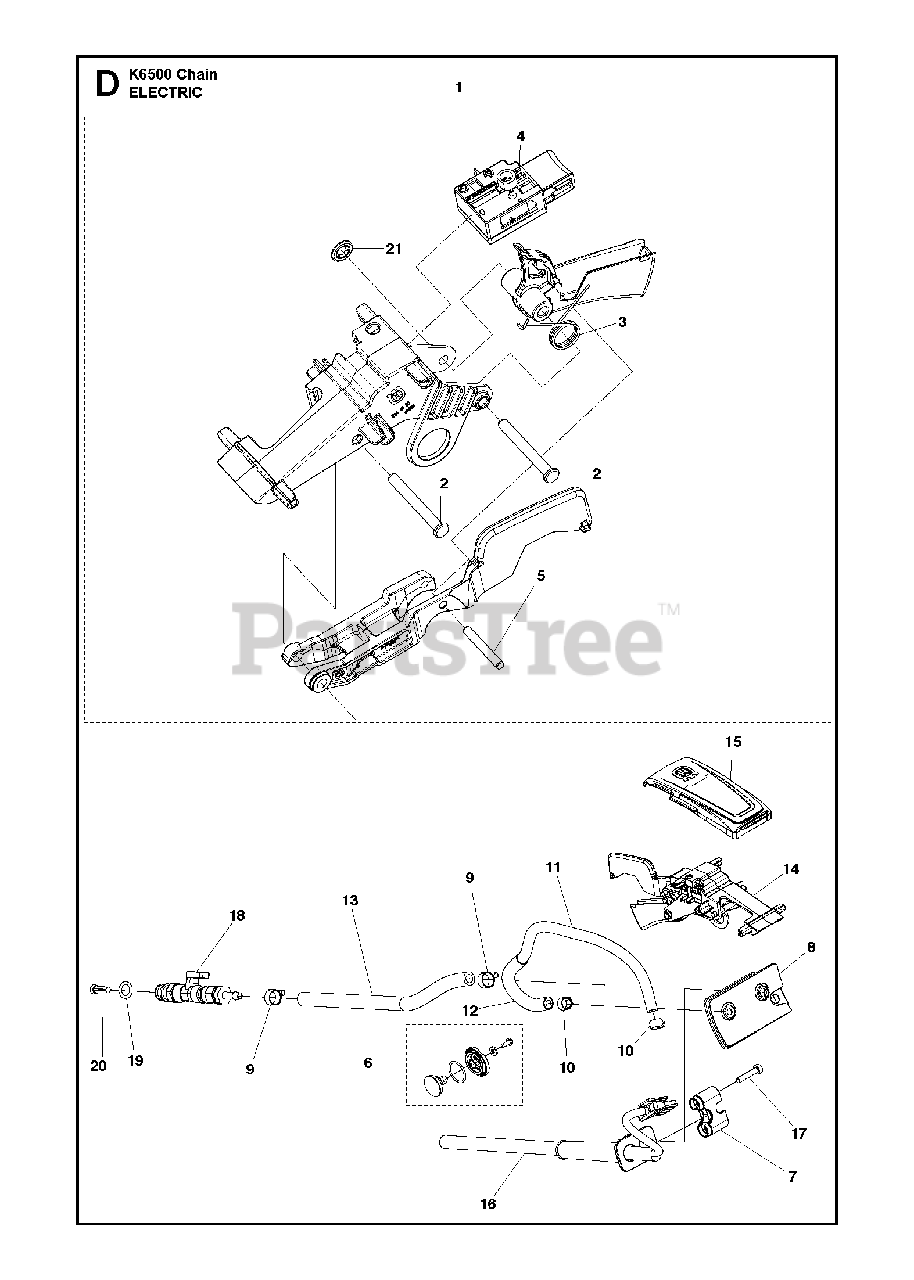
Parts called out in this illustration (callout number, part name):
5	PARALLEL PIN
12	PROTECTIVE SPRING
17	SCREW ITXSCT
